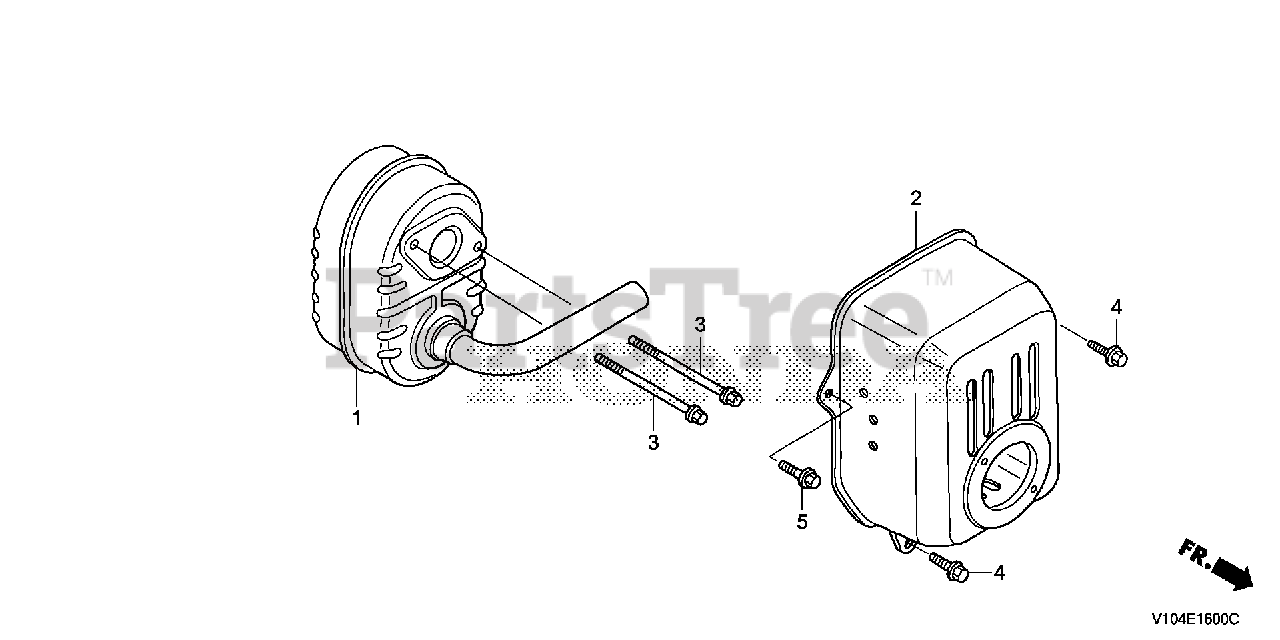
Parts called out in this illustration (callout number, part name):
2	PROTECTOR, MUFFLER
3	BOLT, FLANGE (6X79) (CT200)
4	BOLT, FLANGE (6X12) (CT200)
5	BOLT, FLANGE (6X12) (CT200)
6	GASKET, MUFFLER
